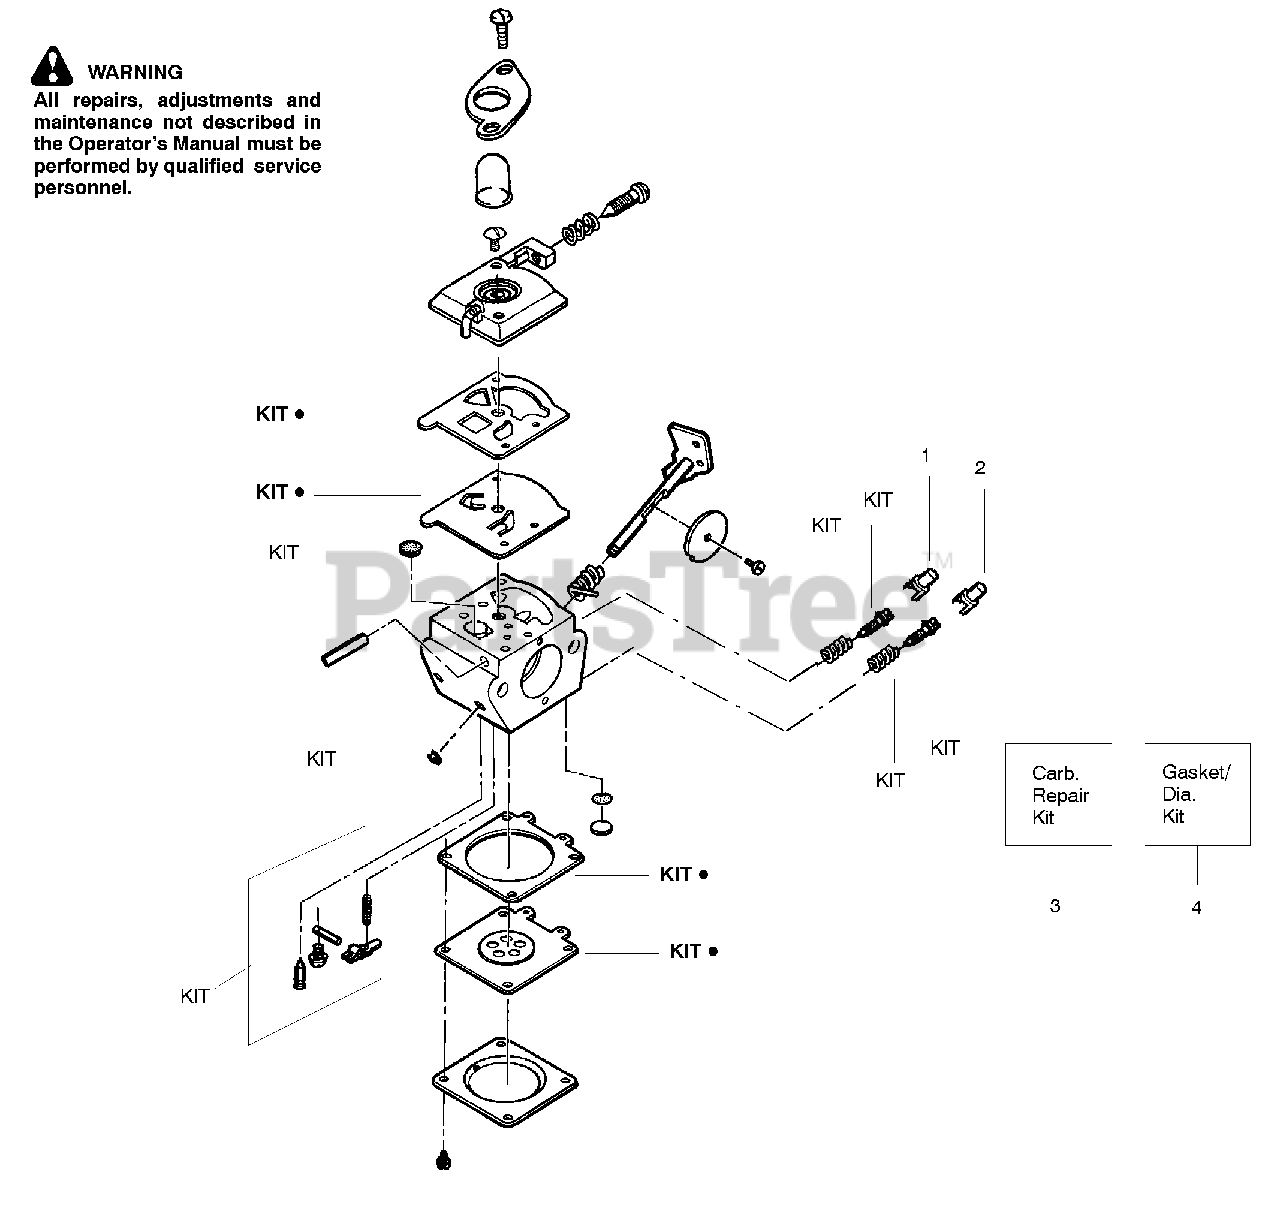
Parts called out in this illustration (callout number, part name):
1	Limiter Cap-Low (tan)
2	Limiter Cap-High (brown)
3	Carburetor Repair Kit ( KIT = CONTENTS)
4	Gasket/Diaphragm Kit (• = CONTENTS)
